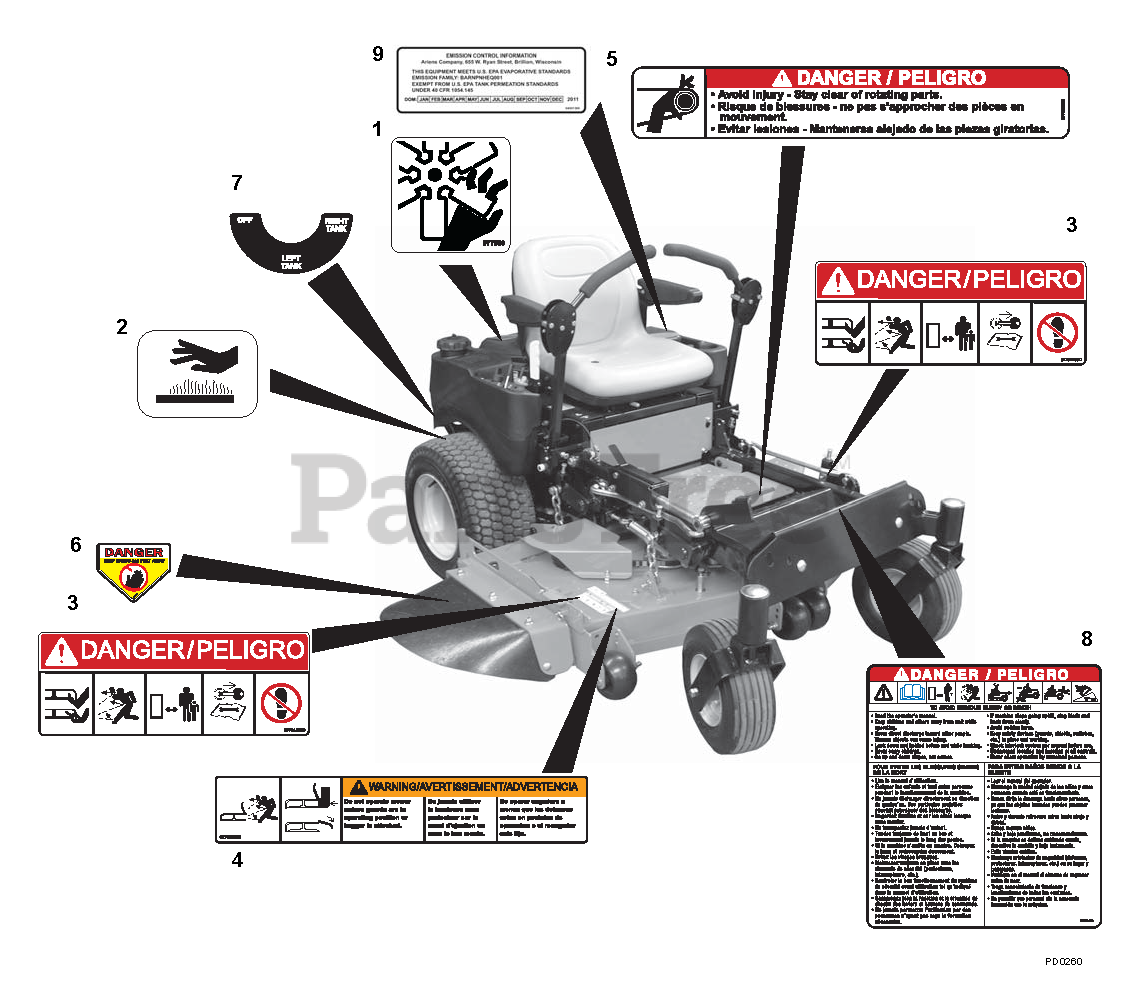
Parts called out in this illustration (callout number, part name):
1	DECAL, DANGER FAN
2	DECAL, HOT SURFACE
3	DECAL, MOWER PAN DANGER
4	DECAL, WARNING
5	DECAL- DANGER
6	DECAL, DANGER
7	DECAL, FUEL VALVE
8	DECAL, DANGER - BILINGUAL
9	LABEL, EPA NON-COMPLIANT TANK
